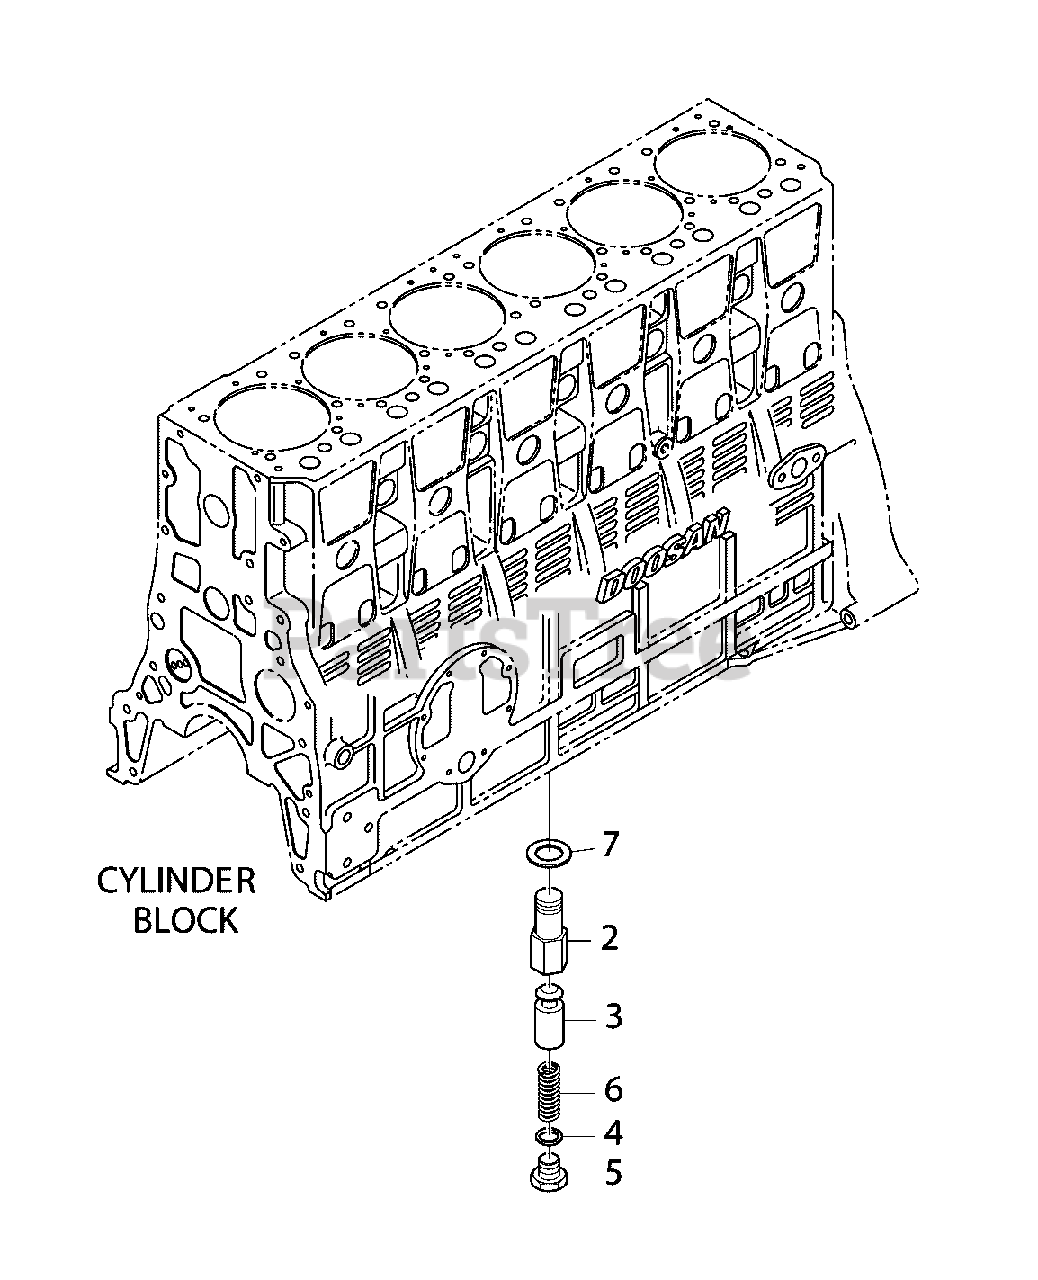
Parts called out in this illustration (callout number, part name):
1	* VALVE, RELIEF
2	* HOUSING
3	* PLUNGER, VALVE
4	* WASHER
5	* PLUG, SCREW
6	* SPRING
